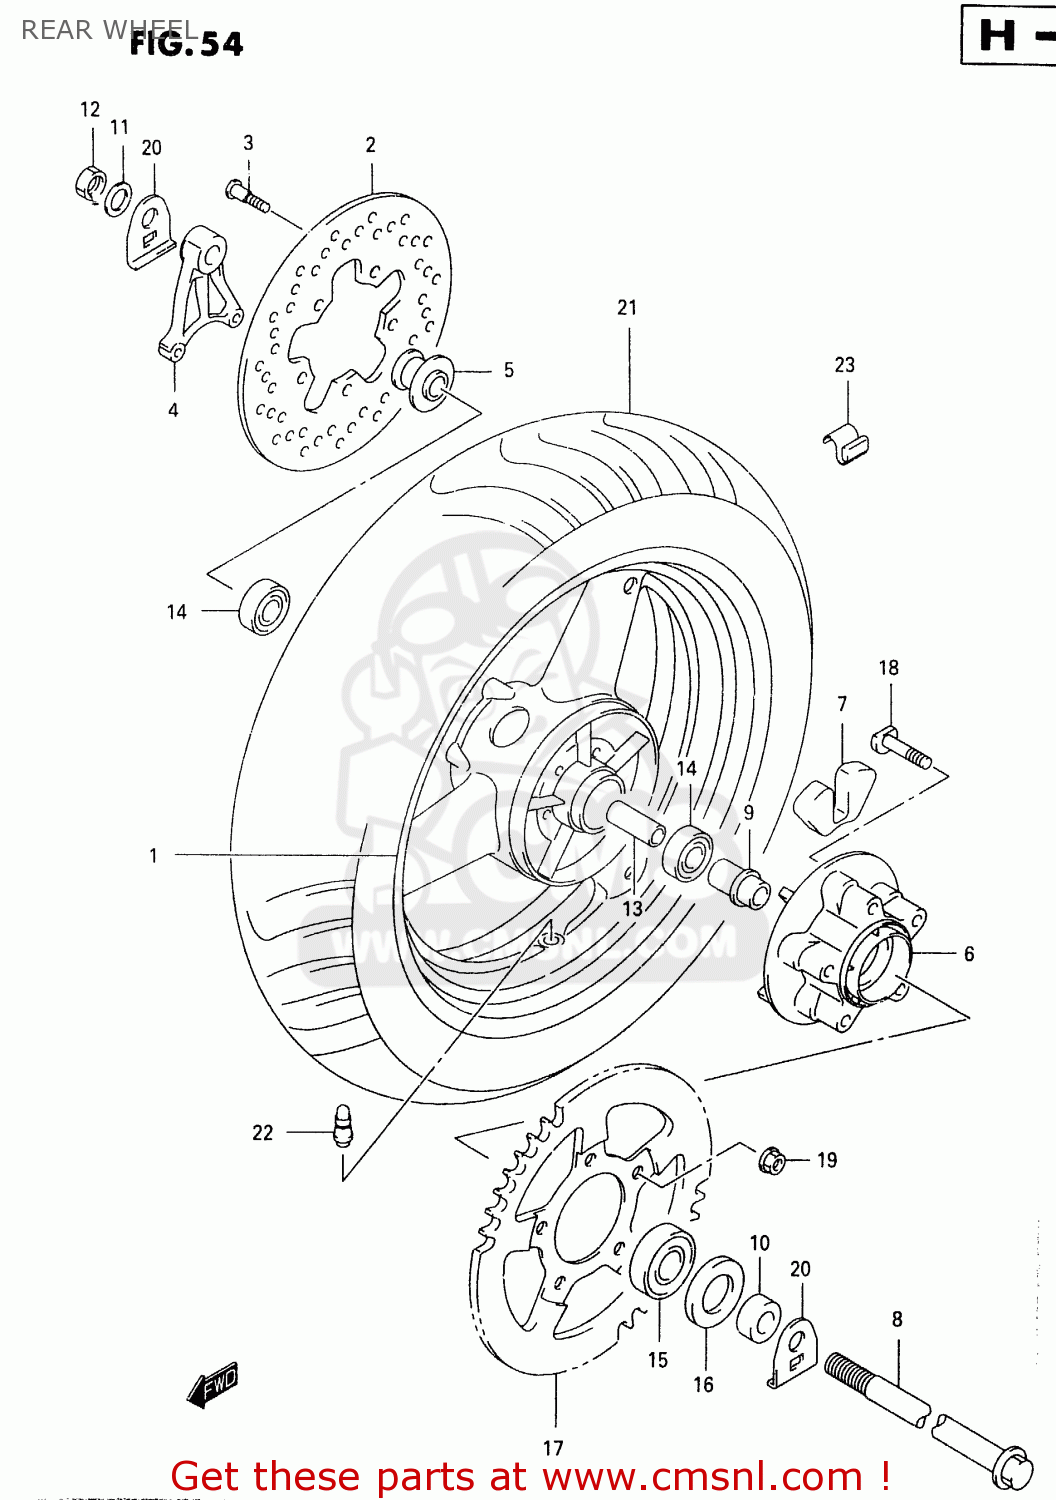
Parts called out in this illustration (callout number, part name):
1	WHEEL,REAR (17XMT4.50)
2	DISC,RR BRAKE
3	BOLT 8X33
4	BRACKET,RR CALIPER
5	SPACER,RR AXLE,R
6	DRUM,RR SPROCKET
7	ABSORBER,RR HUB SHOCK
8	AXLE,RR
9	RETAINER,RR SPROCKET DRUM
10	SPACER,RR AXLE,R
11	WASHER(17X30X3.2)
12	NUT
13	SPACER(17.5X25X88)
14	BEARING
15	BEARING(25X62X17)
16	SEAL,OIL(35X62X8)
17	SPROCKET,RR(NT:47-530)
18	BOLT(10X47)
19	NUT
20	WASHER,CHAIN ADJUSTER
21	TIRE 150/70 ZR17 (69W) M
22	VALVE ASSEMBLY,WHEEL,TR412
23	BALANCER,WHEEL (10G)
